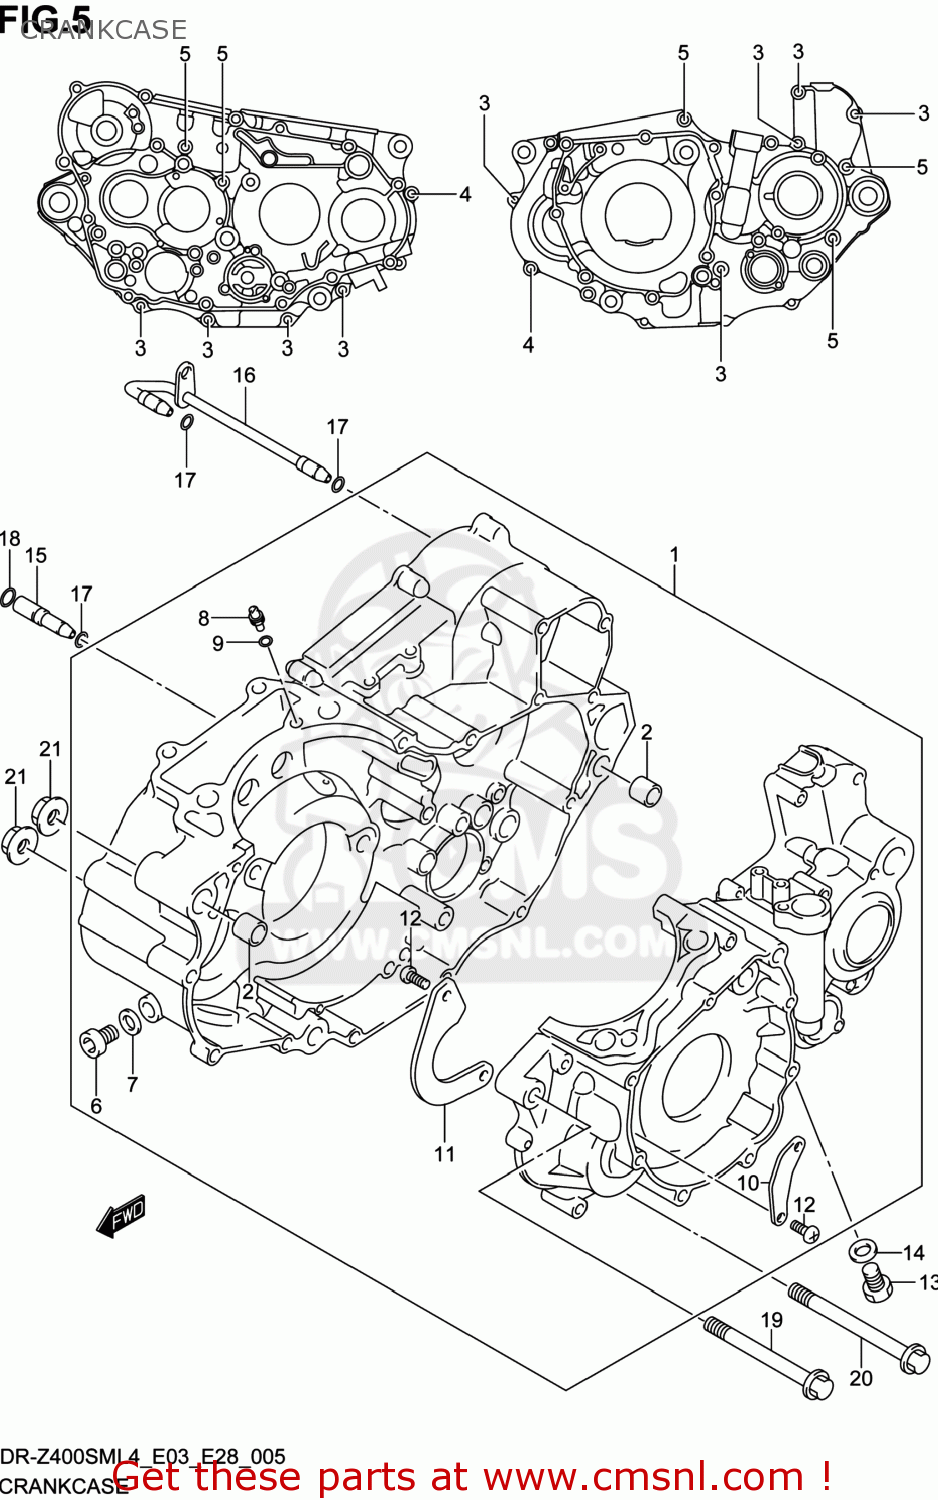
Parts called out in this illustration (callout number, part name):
1	CRANKCASE SET
2	PIN
3	BOLT
4	BOLT
5	BOLT
6	PLUG(10X10)
7	GASKET(10X14X3.6) (NAS)
8	JET(8)
9	O RING(D:1.2,ID:4)
10	SEPARATOR,CRANKCASE OIL NO.1
11	SEPARATOR,CRANKCASE OIL NO.2
12	SCREW(6X12)
13	PLUG(12X20)
14	GASKET(12.1X16.2X3.7) (NAS)
15	PIPE,OIL INNER NO.1
16	PIPE,T/M OIL INNER NO.2
17	O RING(D:1.9,ID:4.8)
18	O RING(D:1.9,ID:6.8)
19	BOLT(10X100)
20	BOLT(10X115)
21	NUT
